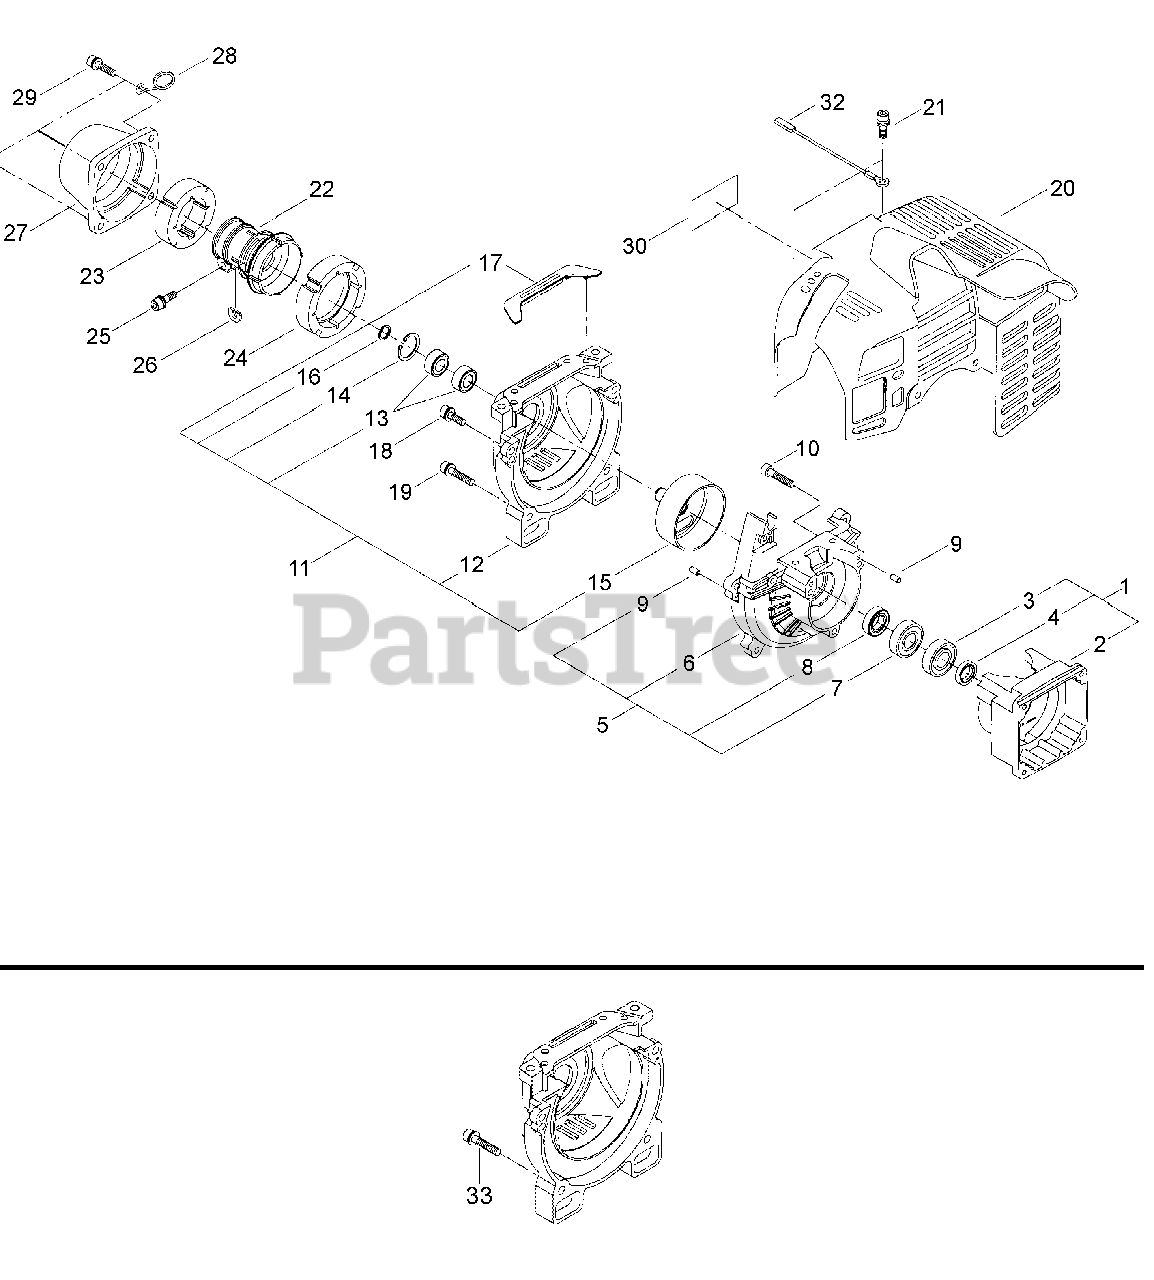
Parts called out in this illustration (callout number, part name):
1	CRANKCASE ASSY, S
2	CRANKCASE S
3	BEARING, BALL 6001 C3
4	SEAL, OIL 12
5	CRANKCASE ASSY, M
6	CRANKCASE M
7	BEARING, BALL 6001 C3
8	SEAL, OIL 12
9	PIN, LOCATING Ø4×8
10	BOLT 5×25
11	FAN CASE ASSY
12	COVER, FAN (RED)
13	BEARING, BALL 6000 DDU
14	RING, SNAP Ø26
15	DRUM, CLUTCH
16	RING, SNAP WR10
18	BOLT M5×16
19	BOLT M5×30
20	COVER, ENGINE - RED
21	BOLT M5×16
22	JOINT
23	CUSHION, FRONT
24	HOLDER, REAR CUSHION
25	BOLT M5×25
26	D-WASHER
27	COVER, AV CUSHION (RED)
28	HOLDER, THROTTLE CABLE
29	BOLT M5×20
30	LABEL - MODEL
32	LEAD - GROUND
33	BOLT M5×25
